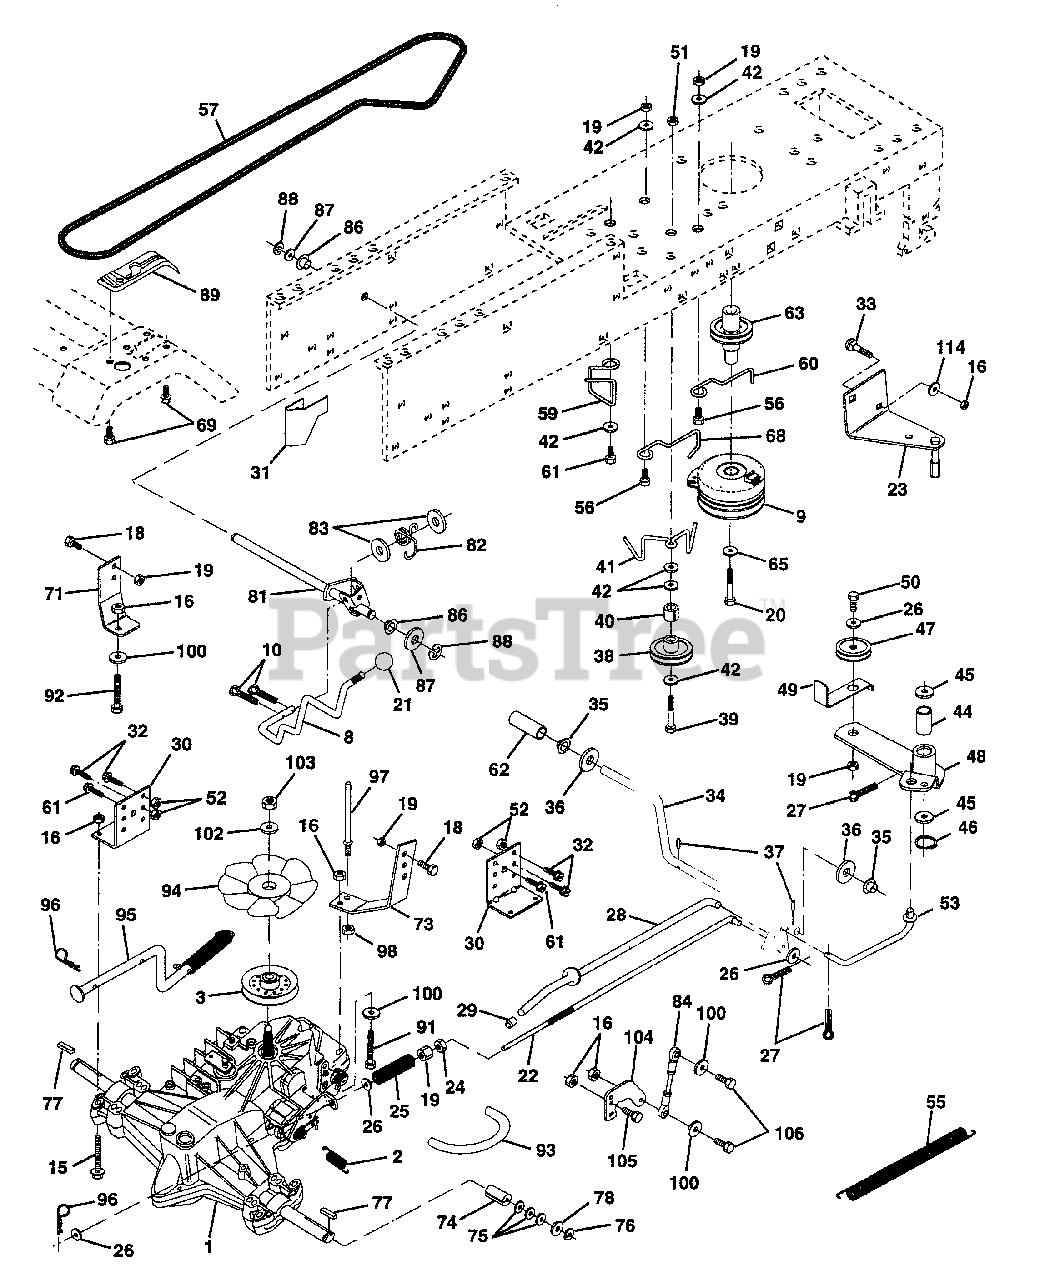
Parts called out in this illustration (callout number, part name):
1	Transaxle Assembly, 310-0650
2	Spring, Return, Brake
3	Pulley, Transaxle
8	Rod Shift Fender y T
9	Clutch, Elect. EVX LT Mag 5217-2
10	Pin Cotter 1/8 x 1 CAD
15	Bolt Hex Flghd 5/16-18 Gr. 5
16	Nut Lock Hex W/Ins. 5/16-18 Unc P
18	Bolt Fin Hex 3/8-16 Unc x 1 Gr. 5
19	Nut Lock Hex W/Wsh 3/8-16 Unc
20	Bolt Hex 7/16-20 x 4-1/4 5 Gal. 38
21	Knob, Deluxe
22	Rod, Brake Hydro
23	Bracket, Asm Clutch Mtg EVX
24	Nut
25	Spring, Brake Rod
26	Washer
27	Pin Cotter 1/8 x 3/4 CAD.
28	Rod, Parking Brake
29	Cap, Parking Brake
30	Bracket, Transaxle
31	Keeper Belt Lh
32	Bolt Hex Hd 5/16-18 Unc x 3/4
33	Bolt Rdhd Sqnk 5/16-18 UNC x 3/4
34	Shaft, Foot Pedal
35	Bearing, Nylon
37	Pin, Roll
38	Pulley, Idler, Flat
40	Spacer, Split
41	Keeper, Belt Idler
42	Washer 13/32 x 13/16 x 12 Gauge
44	Bearing, Nylon
45	Washer, Hardened
46	Ring, Klip
47	Pulley, Idler, V-Groove
48	Bellcrank Assembly
49	Retainer, Belt
50	Bolt
52	Nut Crownlock 5/16-18
53	Link, Clutch
55	Spring, Return, Clutch
56	Bolt Fin Hex 3/8-16 UNC x 1-1 /4
57	V-Belt, Ground Drive
59	Keeper, Center Span
60	Keeper Belt Engine
61	Screw Thdrol. 3/8-16 x 3/4 Ty. TT
62	Cover, Pedal
63	Pulley, Clutch Electric EVX
65	Washer
68	Keeper Belt Engine
71	Strap Torque Lh Hydro
73	Strap Torque Rh Hydro
74	Spacer, Split
75	Washer 25/32 x 1-1/4 x 16 Gauge
77	Key, Square
78	Washer 25/32 x 1-5/8 x 16 Gauge
81	Shaft Asm. Cross Hydro
82	Spring Torsion T/A
83	Washer 17/32 x 3/4 x 16 Ga.
84	Rod, Tie Hydro
86	Bushing Rod Steering 629/632 ID
87	Washer 21/32 x 1-1/4 x 16 Ga.
88	Ring Klip #5304-62
89	Console, Shift
91	Bolt Fin Hex 5/16-18 x 2-1/4
92	Bolt Fin Hex 5/6-18 Unc x 1-1/2
93	Line Fuel Hydro 4"
94	Fan, Hydro 7"
95	Control Bypass Hydro
96	Retainer Spring 1" Zinc/Cad
97	Keeper Belt Rh Hydro
98	Nut Keps Hex 3/8-16 Unc
100	Washer 11/32 x 3/4 x 16 Ga.
102	Washer, Bellville .50 ID x 1.50 D
103	Nut Nylon Insert 1/2-20 Unf.
104	Arm, Control Hydro
105	Screw Cap Hex 5/16 x 18 x 1
106	Bolt Fin Hex 5/16-18 Unc x 1-1/4
114	Washer 11/32 x 3/4 x 14 Ga.
